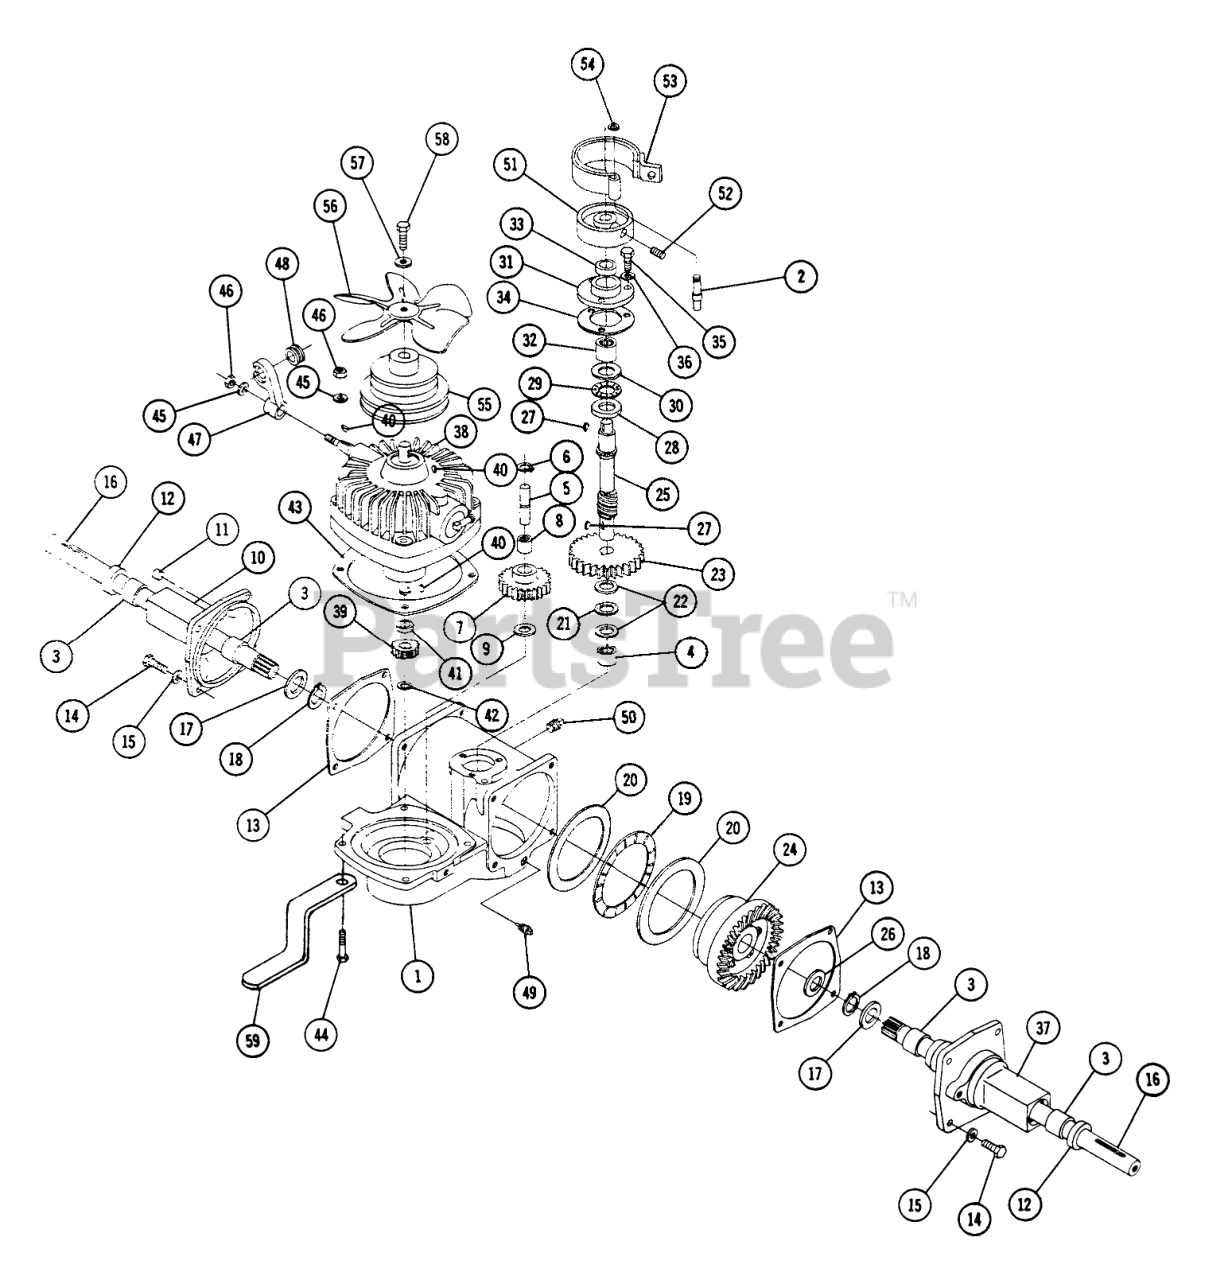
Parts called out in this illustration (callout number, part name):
1	Housing
2	Pin-Pivot-Brake
3	BEARING-NEEDLE
4	BEARING-NEEDLE
5	Pin-Idler Gear
6	Snap Ring
7	GEAR -SPUR - IDLER
8	Bearing-Needle
9	RACE THRUST
10	Housing-Axle R H.
11	Breather
12	Seal Oil 1" I.D.
13	GASKET
14	Bolt 3/8-16 x 1
15	LOCKWASHER
16	Axle
17	Gear-36T
18	Snap Ring
19	Bearing Thrust
20	Race-Thrust
21	BEARING-THRUST
22	Race Thrust
23	Gear-Spur-Pinion Drive
24	Differential
25	Pinion-Gear-Differential
26	Washer
27	KEY WOODRUFF
28	BEARING RACE SPECIAL
29	Bearing-Thrust
30	Rae-Thrust
31	End Cap-Pinion
32	Bearing Needle
33	Seal 5/8 I.D.
34	GASKET END CAP
35	Bolt 5/16-18 x
36	Lockwasher
37	Housing Axle L.H.
38	Engine Speed Control
39	Gear-Spur-Input
40	KEY WOODR 1/8X1/2 DI
41	Spacer
42	SNAP RING
43	GASKET HYDRO
44	Bolt Hex 3/8-16 x 5
45	Washer
46	3/8-16 E.S.
47	Lever-Control
48	Grommet-Rubber
49	Plug 1/4 Pipe
50	SOLID PIPE PLUG
51	Brake Drum
52	Screw 1/4-20 x 5/8
53	BRAKE BAND & LINER
55	Pulley-Transmission
56	FAN
57	Washer-Special
58	Bolt Hex 1/4-20 x 1 1/4 Nylok
59	Bracket
